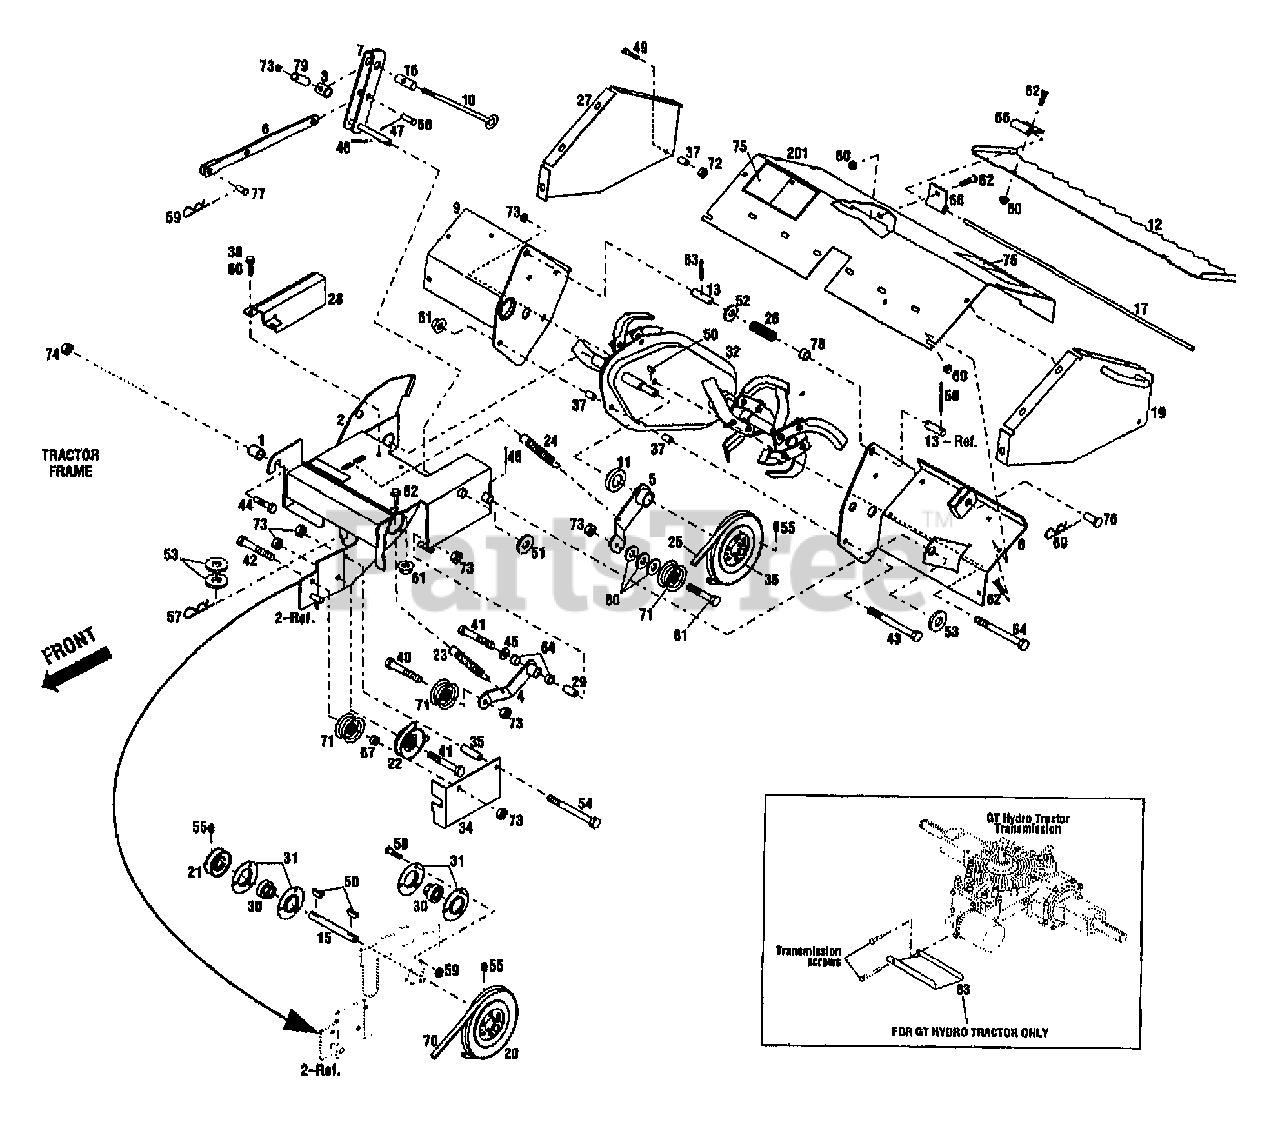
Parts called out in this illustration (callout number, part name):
1	SPACER-ATTACHMENT
2	HITCH-TILLER
3	SPACER-1.0X.782X.81
4	ARM-IDLER
5	ARM-IDLER
7	ARM-PIVOT
8	PLATE-TINE COVER LH
9	PLATE-TINE COVER RH
10	ROD-PIVOT ARM
11	WASHER-CUP 2.12X1.18X.44
12	SHIELD-TINE HOOD
15	DRIVESHAFT-PULLEY
17	PIN-HINGE
19	COVER-TINE HOOD LH
20	PULLEY-6" DIA
21	PULLEY-2.50" DIA.
22	PULLEY-IDLER 3" DIA
23	SPRING-EXTENSION
24	SPRING-EXTENSION
25	BELT-V 30"
26	SPRING-COMPRESSION
27	COVER-TINE HOOD RH
28	COVER-BELT
29	SPACER-.625X.39X1.25
30	BEARING-BALL
31	BEARING-FLANGE
32	TRANSMISSION
34	SHIELD-DEBRIS
35	SPACER-.625X.406X2.12
37	SPACER-.375X.812
38	SCR-HHC 5/16-18X.75 GR 5 ZP
41	SCR-HH 3/8-16X2.0 G5 ZP
42	SCR-HH 3/8-16X2.25 G5 ZP
43	SCR-HH 3/8-16X2.50
44	SCR-HH 1/2-13X1.5 G5 ZP
45	WASHER-.986X.437X.083 ZP
46	PIN-COTTER .125 X .75 ZP
47	PIN-COTTER .120X1.00 ZP
48	PIN-COTTER .120X1.25 ZP
49	SCR-HH 5/16-18X1.5 G5 ZP
50	KEY-WOODRUFF .188X.75
51	WASHER-1.06X.531X.1 ZP
52	WASHER-1.305X.649X.098 ZP
53	WASHER-1.5X.812X.134 ZP
54	SCR-HH 3/8-16X3.0 G5 ZP
55	SCR-SET
57	PIN-HITCH .149DIA
58	SCR-CARR 1/4-20X.75 G2 ZP
59	NUT-HF/LK 1/4-20 ZP
60	NUT-HFLK 5/16-18 ZP
61	NUT-HFLK 3/8-16 ZP
62	SCR-CARR 5/16-18X.75
63	PIN-ROLL .156X1.0
64	BUSHING-FLANGE
66	HINGE-HOOD
67	SPACER-.625X.406X.563
68	PIN-CLEVIS .5X1.75 ZP
69	PIN-HITCH .125X2.56 ZP
70	BELT-V
71	PULLEY-IDLER
72	NUT-TOP/LK 5/16-18 ZP
73	NUT-LOCK 3/8-16
74	NUT-TOP LOCK 1/2-13 ZP
75	DECAL-OPEI CAUTION
76	PIN-CLEVIS .625X1.44
77	PIN-CLEVIS .5X1.06 ZP
78	SPACER-.875X.63X.5
79	SPACER-.625X.406X.563
80	WASHER-FLAT 3/8 SAE
81	SCR-HH 3/8-16X1.75 G5 ZP
93	KIT-SHIFT ON FLY LOCKOUT
201	HOOD W/DECALS
